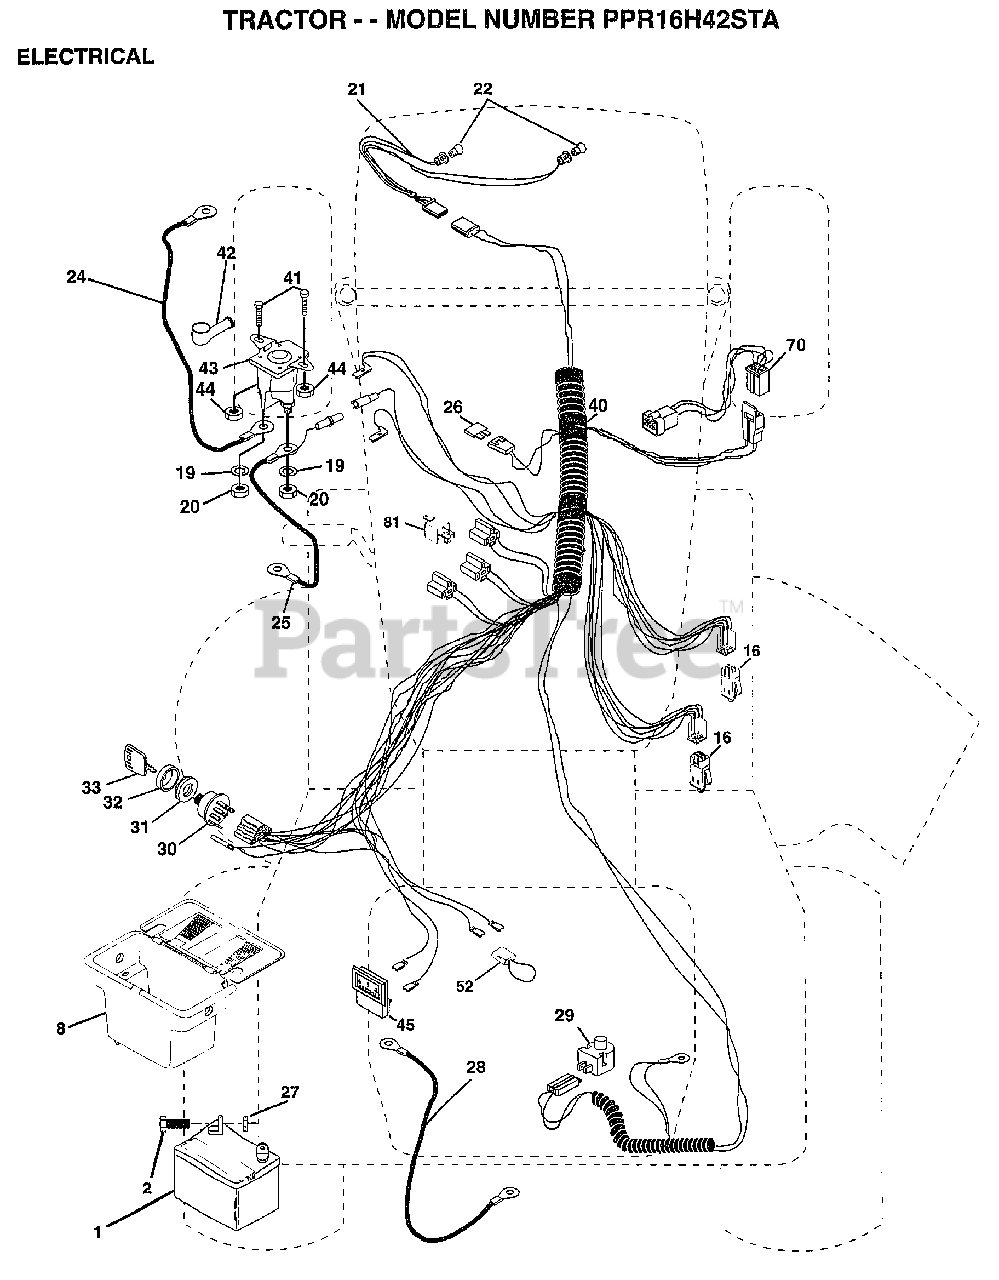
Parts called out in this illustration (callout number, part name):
2	BOLT LT
8	"CASE,BATTERY.MECH"
16	SWITCH.INTERLOCK
20	NUT
21	HARNESS.ASM.LIGHT W/4152J
22	HEADLAMP BULB
24	"CABLE T, BATTERY"
25	CABLE.BTRY.6GA.RD
26	FUSE.15 AMP
27	NUT
28	CABLE T
29	SWITCH.PLUNGER
30	SWITCH IGN 4POS
31	NUT IGNITION
32	COVER KEY SWITCH
33	KEY
40	HARNESS IGNITION
41	BOLT HXHD FIN
44	NUT HXKEP 1/4X20
45	AMMETER
52	PROTECTION LOOP
70	HARNESS.ENG.TEC/KOHL
81	RELAY ASSY T
